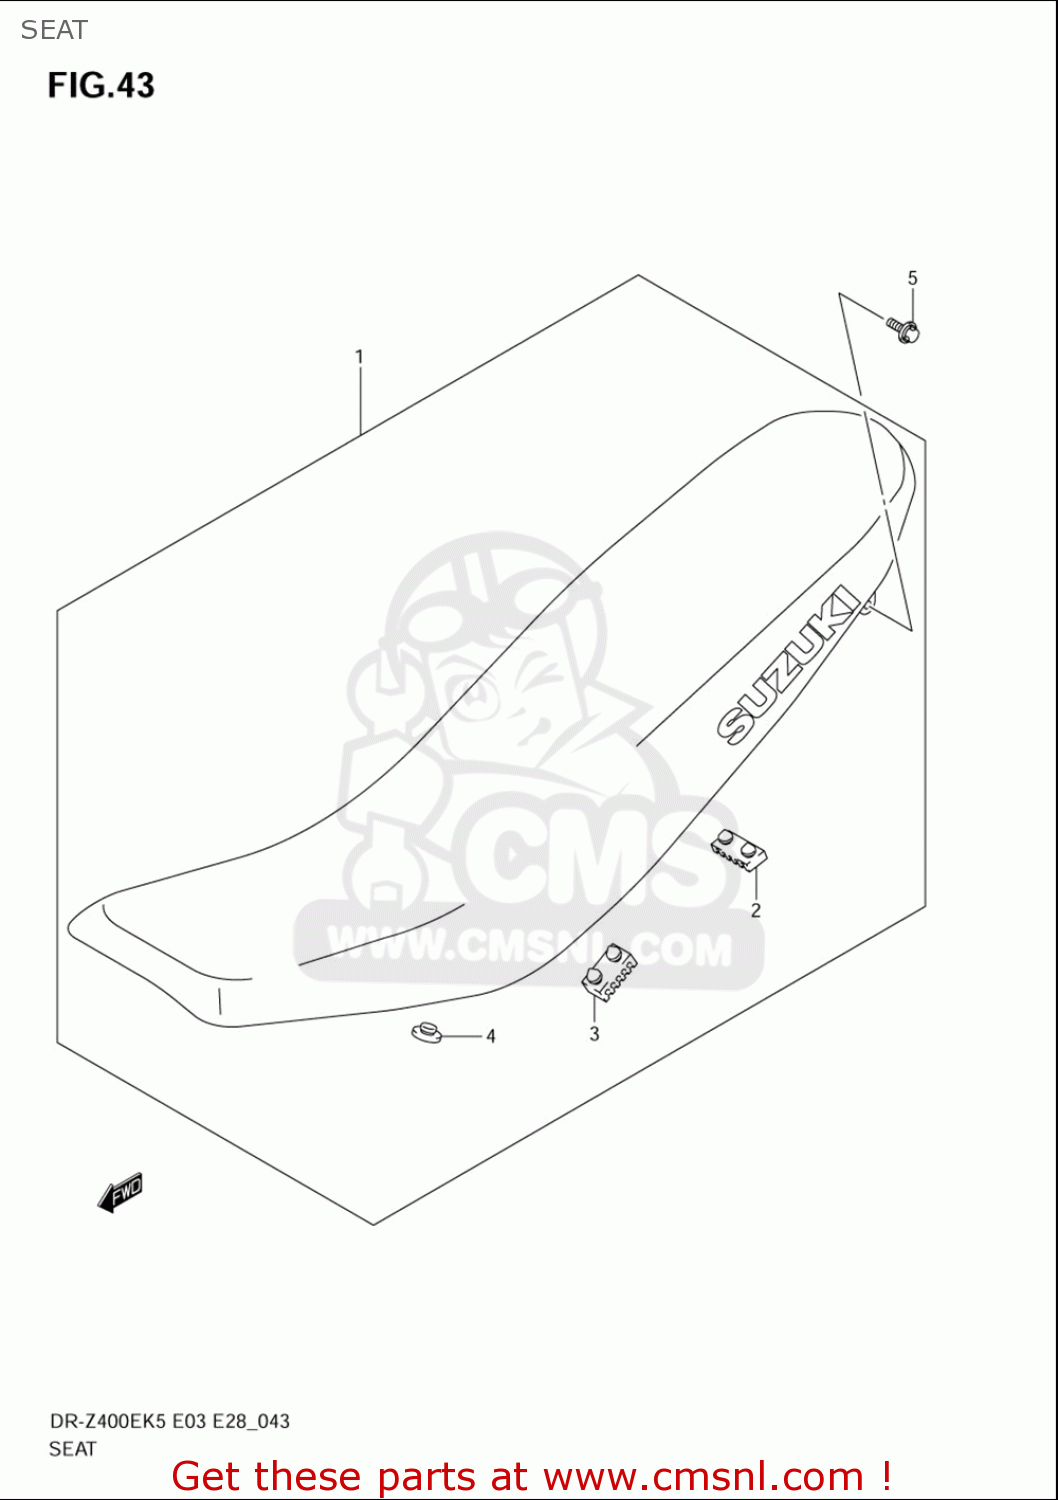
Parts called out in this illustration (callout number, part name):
1	SEAT ASSY
2	CUSHION,SEAT(40X20X6)
3	CUSHION,SEAT(40X20X15)
4	CUSHION
5	BOLT
